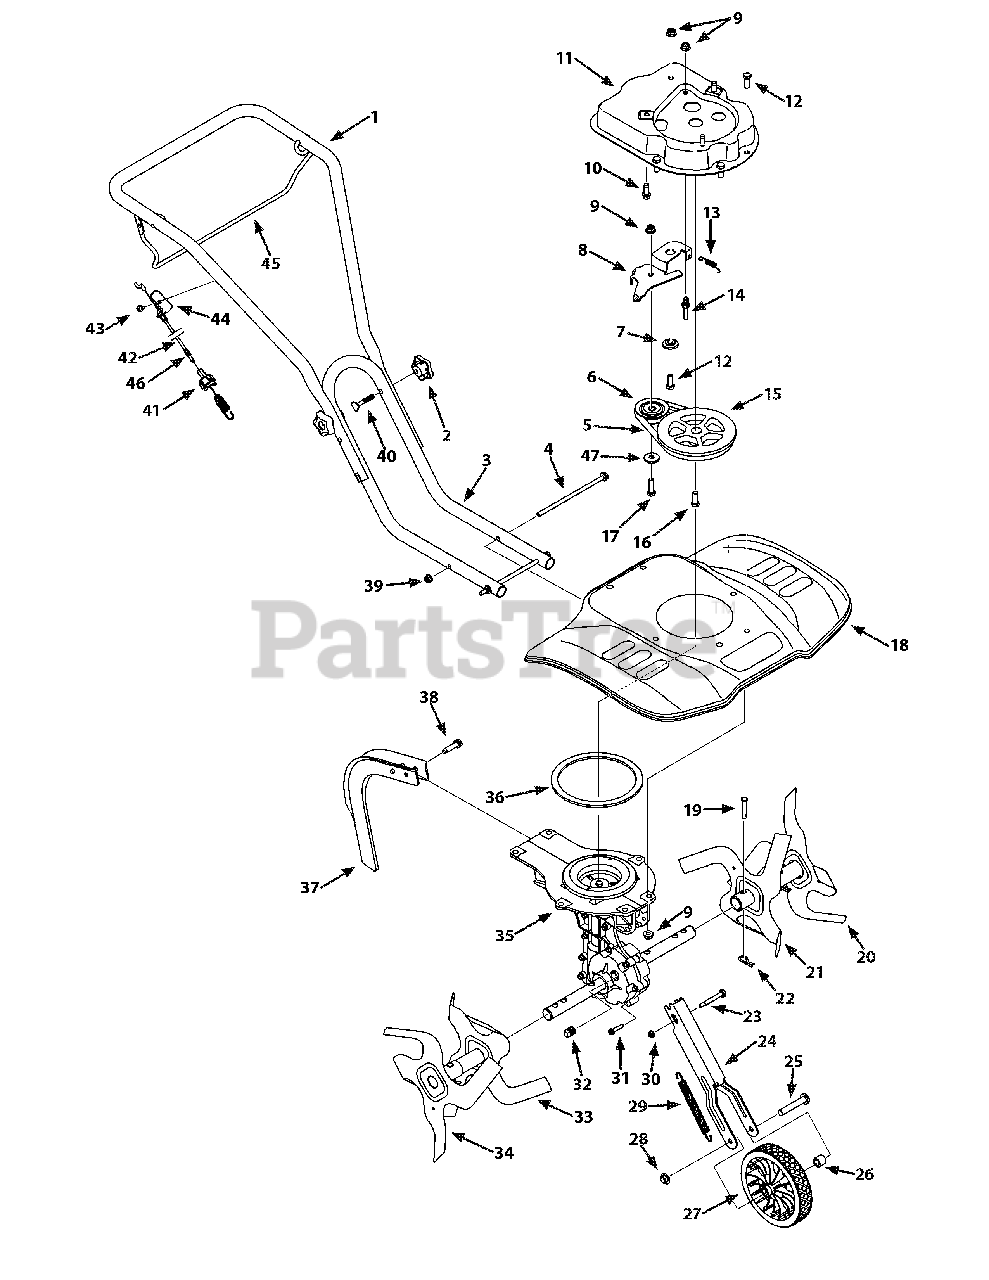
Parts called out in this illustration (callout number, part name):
1	Upper Handle
2	Star Handle Knob
3	Lower Handle
4	Flange Screw: 5.16-18:7.5:GR5
5	V-Belt
6	Idler Pulley
7	Shoulder Spacer
8	Idler Bracket
9	Flange Lock Nut: 3.8-16
10	TT Screw: 3.8-16:1.00
11	Belt Cover
12	HH Cap Screw: 3.8-16:1.00
13	Extension Spring
14	Stud: 33 x 1.5: 3.8-16
15	Flywheel Pulley
16	HH Cap Screw: 3.8-24:1.00
17	HH Cap Screw: 3.8-16:1.55
18	Tine Shield 61 cm
19	Clevis Pin
20	Outer Tine Assembly LH
21	Inner Tine Assembly LH
22	Internal Cotter Pin
23	Shoulder Screw: .31x2:1.4-20
24	Front Wheel Bracket
24	Front Wheel Axle Hardware Kit
25	Clevis Pin
26	Spacer
27	Wheel 7x1.5 Star-Diam
28	Push Cap
29	Extension Spring
30	Flange Lock Nut: 1.4-20
31	TT Screw: 1.4-20:1.25
32	Pipe Plug: 3.8 NPT
33	Inner Tine Assembly RH
34	Outer Tine Assembly RH
35	Case Assembly
36	Gasket
37	Depth Stake Assembly
38	TT Screw: 3.8-16:1.50
39	Flange Lock Nut: 5.16-18
40	Carriage Bolt
41	Clutch Cable Fitting
42	Clutch Cable
43	TT Screw: 1.4-20:.50
44	Cable Mount Bracket
45	Clutch Bail
46	Retaining Ring
47	Flat Washer, .406 x .875 x .059
